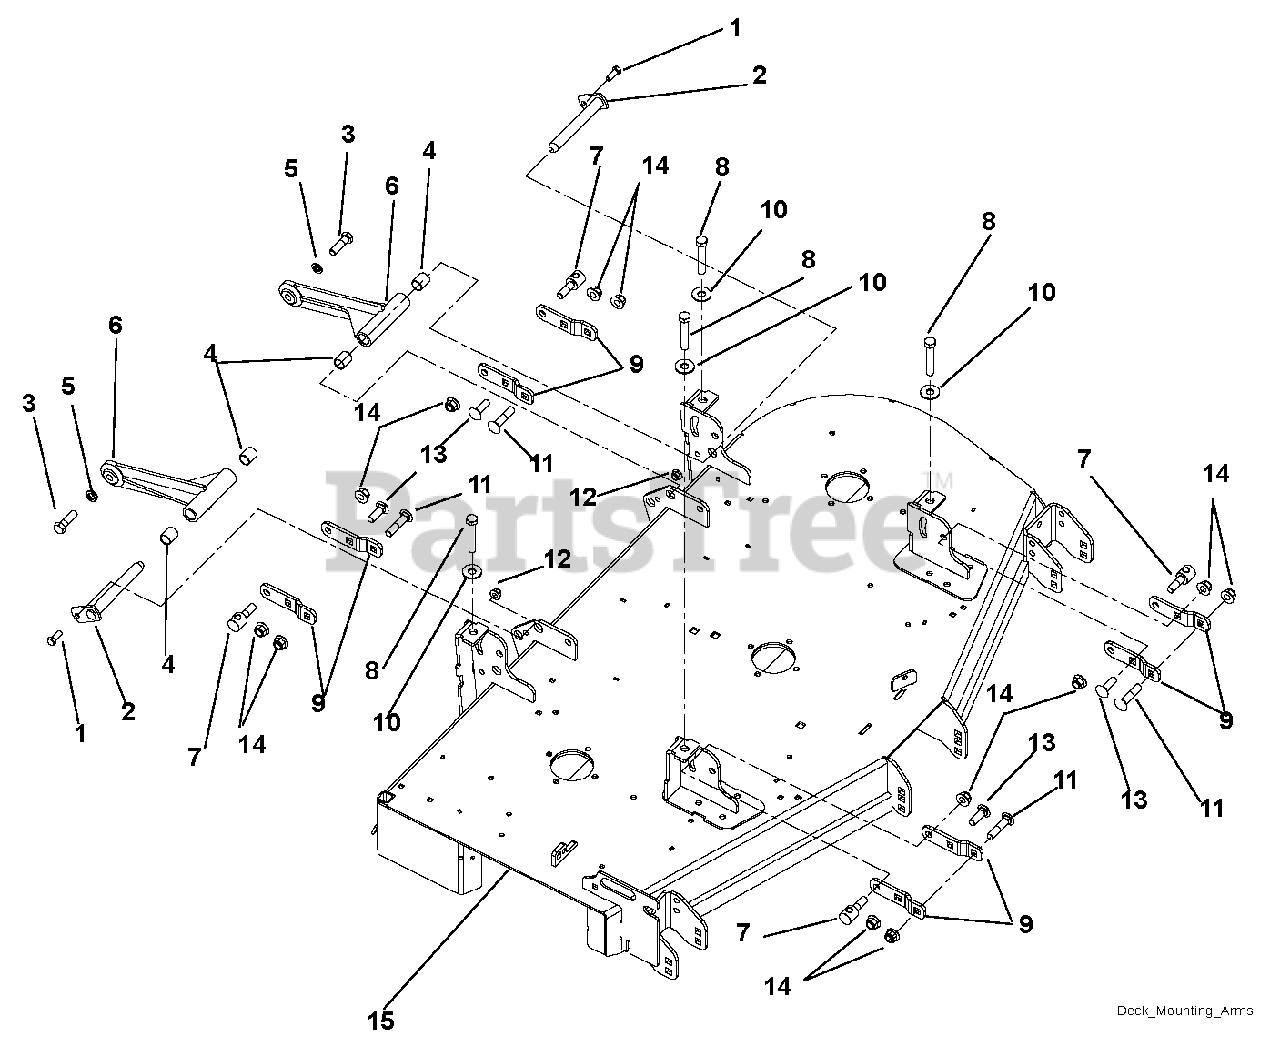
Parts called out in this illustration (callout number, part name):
1	Bolt, Hex .38-16 x 1.00
2	Weldment, Mower Mounting Pin
3	Bolt, Hex .50-13 x 1.75 Grade 5 EP80
4	Bearing, .75 x .875 x 1.00
5	Washer, Locking .50 x .125 Regular
6	Deck Pusher Arm Weldment, Black
7	Trunnion, .50-13
8	Bolt, Hex .50-13 x 3.00
9	Bracket, Deck Leveling
10	Washer, Flat Steel .563 x 1.38 x .109
11	Bolt, Round Head Square Neck .50-13 x 2.25
12	Nut, Locking Nylon Flange .38-16
13	Bolt, Round Head Square Neck .50-13 x 1.50
14	Nut, Locking Nylon Flange .50-13
15	Weldment, 48" Side Discharge Deck (991079, 095, 102)
